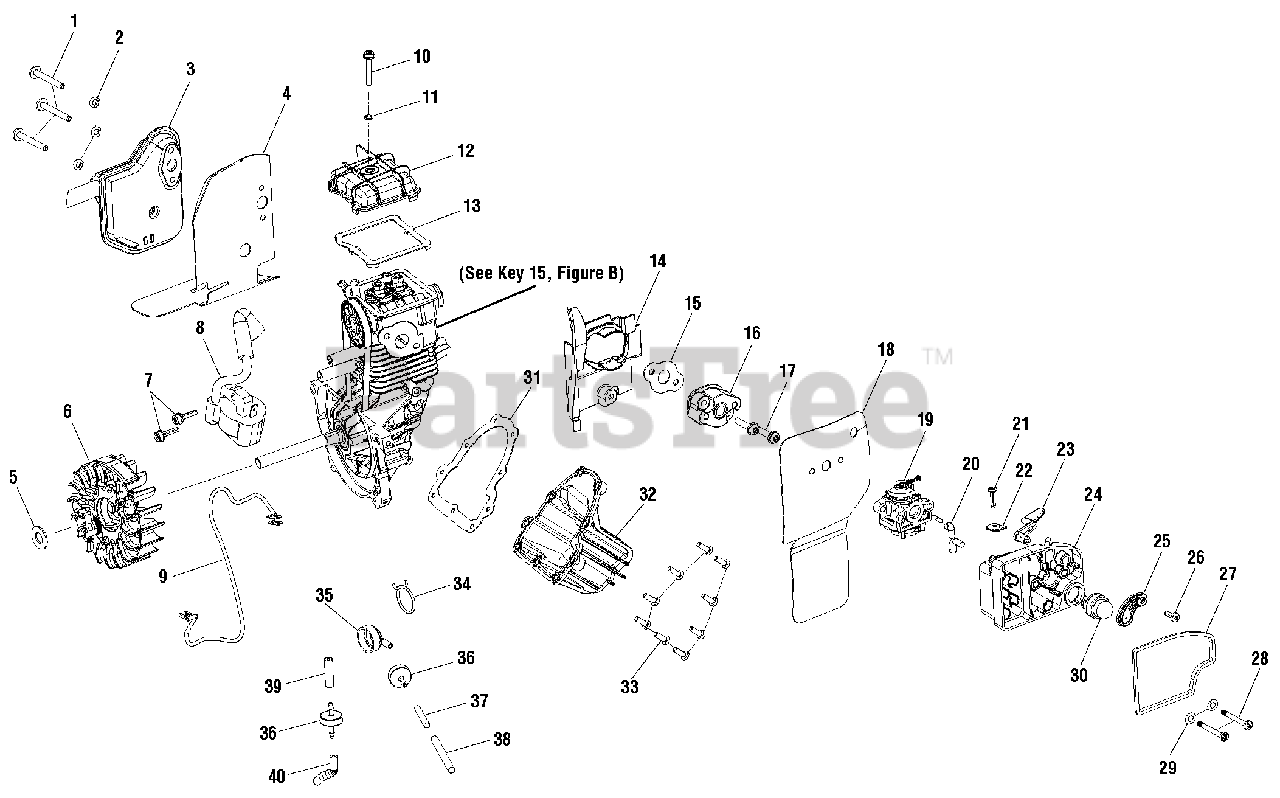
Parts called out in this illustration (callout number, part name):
1	Screw (M5 x 42 mm, T25 Truss Hd.)
2	Lock Washer (M5)
4	Muffler Gasket
5	Washer (ID9.70 x OD20 x 1.59t)
6	Flywheel Assembly
7	Screw (M4 x 19 mm, T20 Torx Pan Hd.)
8	Ignition Module
9	Lead Assembly
10	Screw (M4 x 27 mm, T20 Torx Truss Hd.)
12	Cam Cover
14	Air Baffle
15	Heat Gasket
17	Screw (M5 x 23 mm, T25 Torx pan Hd.)
19	Carburetor
20	Fuel Hose (90 mm)
21	Screw (M4 x 16 mm, T20 Pan Hd.)
23	Choke Lever
24	Air Box Base
25	Choke Plate
26	Screw (M4 x 12 mm, T20 Torx Pan Hd.)
27	Air Box Seal
28	Bolt (M5 x 48 mm, T20 Torx hd.)
29	Washer (ID5 x OD9.90 x 1t)
30	Primer
33	Screw (M4 x 12 mm, T20 Torx Hd.)
35	Breather Fitting
36	Check Valve
37	Fuel Hose (53 mm)
38	Shield Sleeve (50 mm)
39	Breather Hose (34 mm)
40	Breather Hose (25 mm)
